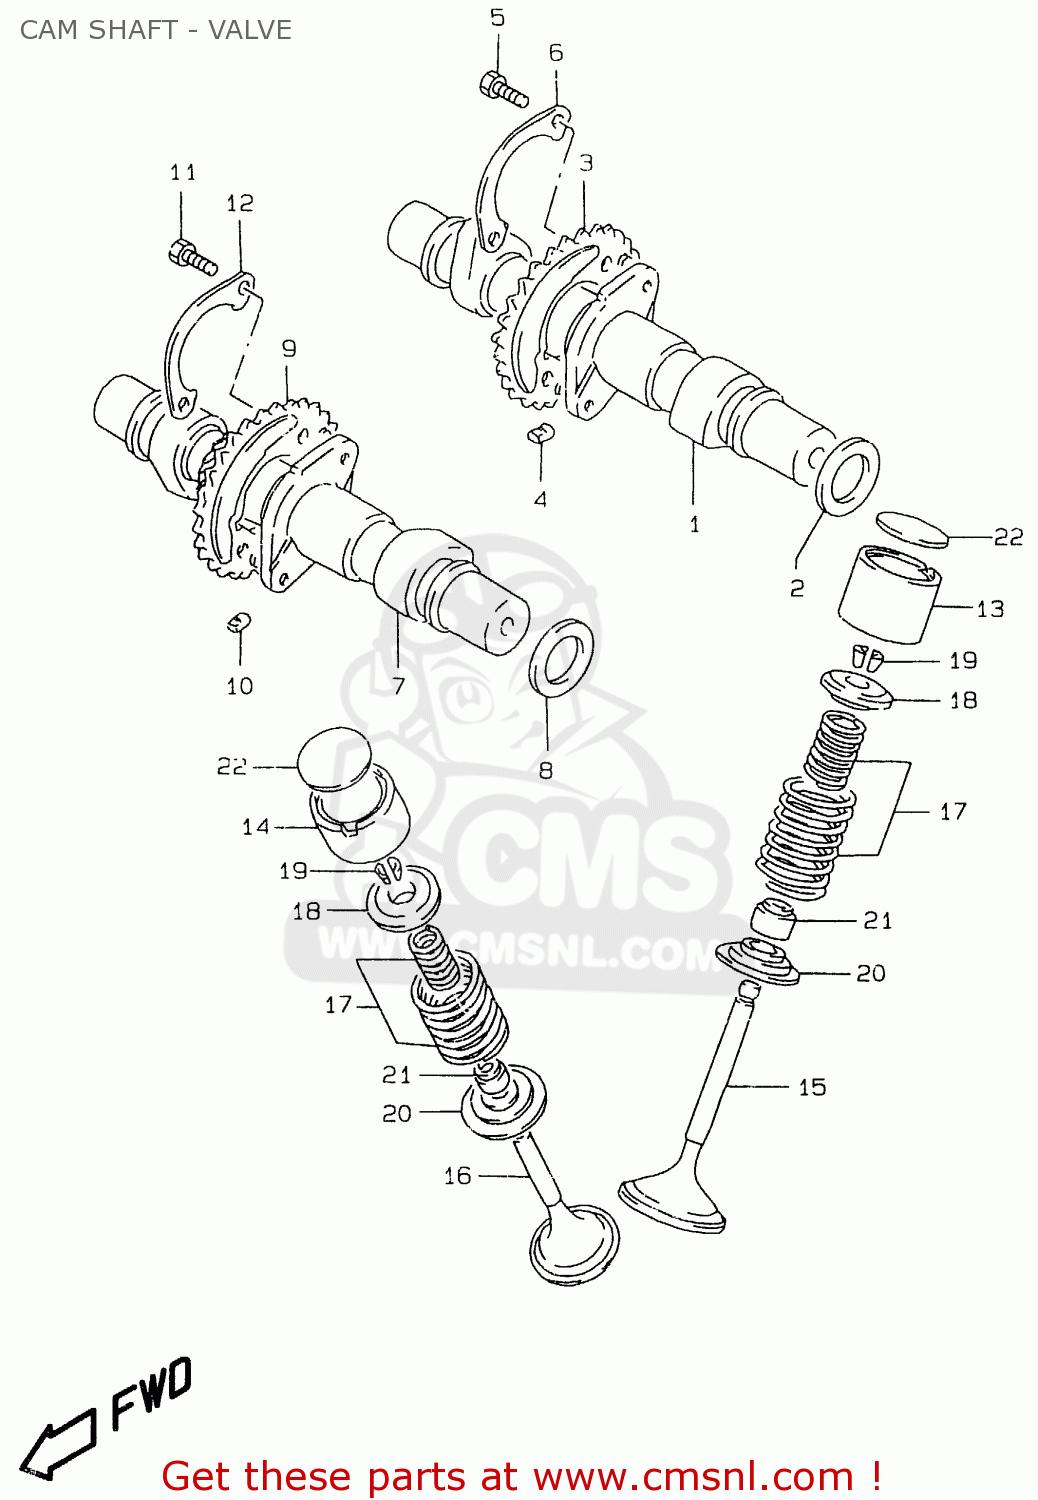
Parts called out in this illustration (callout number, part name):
1	CAMSHAFT SET,INTAKE
2	SHIM(22X30X1)
3	SPROCKET,CAMSHAFT INTAKE
4	PIN,SPROCKET
5	BOLT(6X12.5)
6	WASHER,CAM CHAIN SPROCKET
7	CAMSHAFT SET,EXHAUST
8	SHIM(22X30X1)
9	SPROCKET,EXHAUST CAM(NT:30)
10	PIN,SPROCKET
11	BOLT(6X12.5)
12	WASHER,CAM CHAIN SPROCKET
13	TAPPET
14	TAPPET
15	VALVE,INTAKE
16	VALVE,EXHAUST
17	SPRING SET,VALVE
18	RETAINER,VALVE SPRING
19	COTTER VALVE
20	SEAT,VALVE SPRING
21	SEAL,OIL(7X14.4X9)
22	SHIM,TAPPET(T:2.15)
